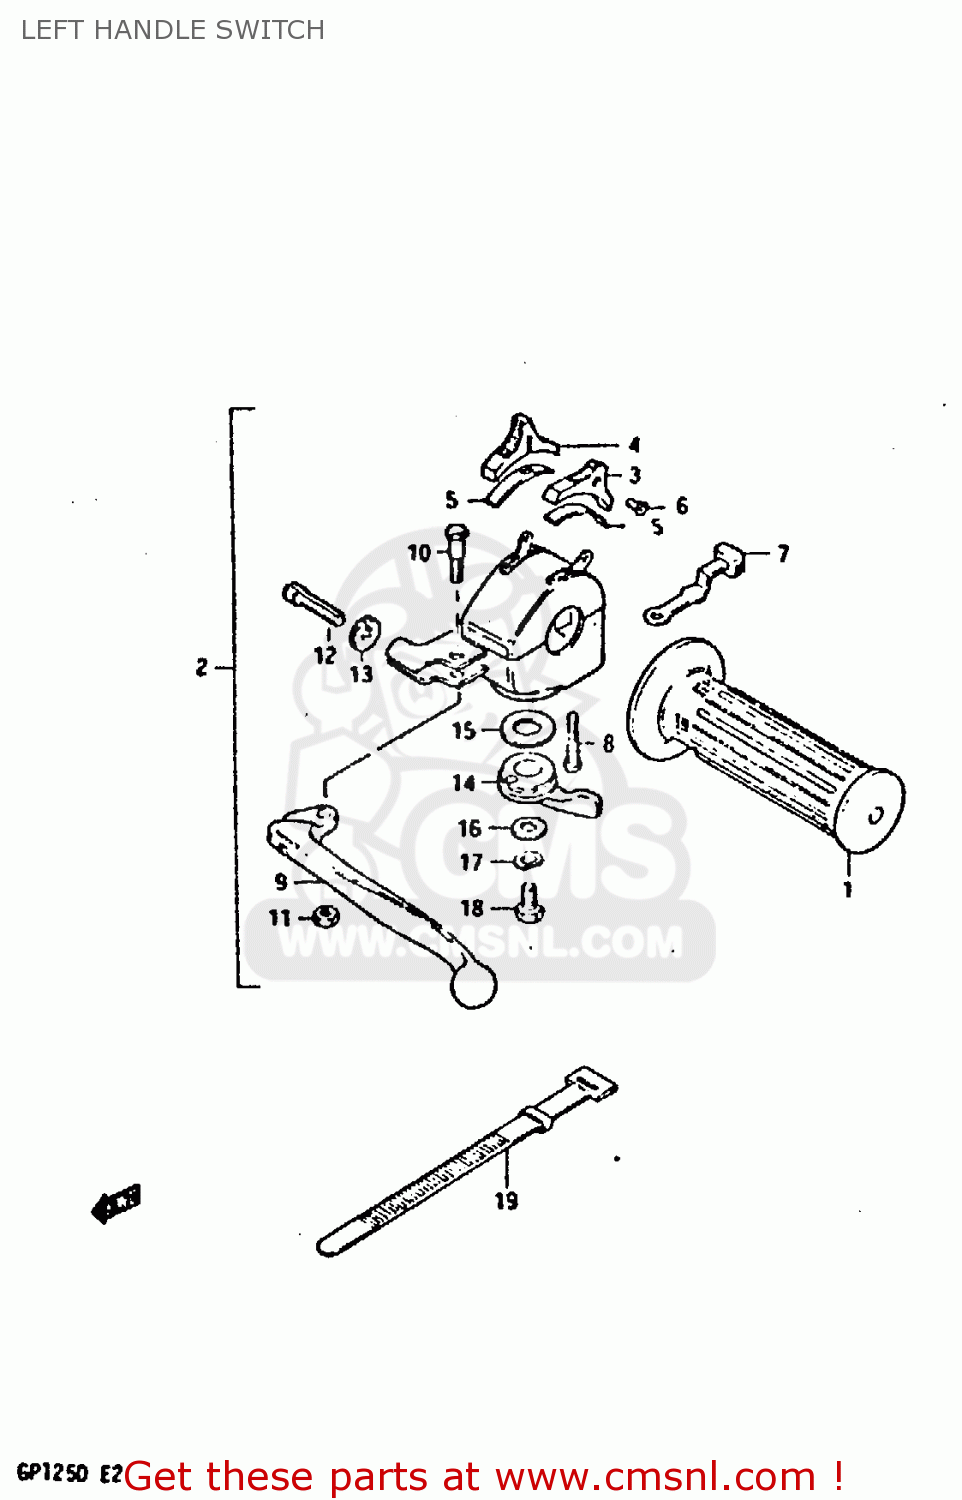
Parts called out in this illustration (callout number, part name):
1	GRIP,L
2	LEVER ASSY,CLUTCH
3	KNOB,HANDLE SWITCH
4	KNOB,HANDLE SWITCH
5	PLATE,SWITCH KNOB
6	SCREW
7	LEVER,TURN SIGNAL
8	SCREW 5X20
9	LEVER,CLUTCH
10	BOLT
11	NUT 6MM
12	ADJUSTER,CABLE
13	NUT,CABLE ADJUSTER
14	LEVER,STARTER
15	WASHER,ADJUSTER
16	WASHER,STARTER LEVER
17	LOCK WASHER
18	BOLT
19	CLAMP(L:120)
